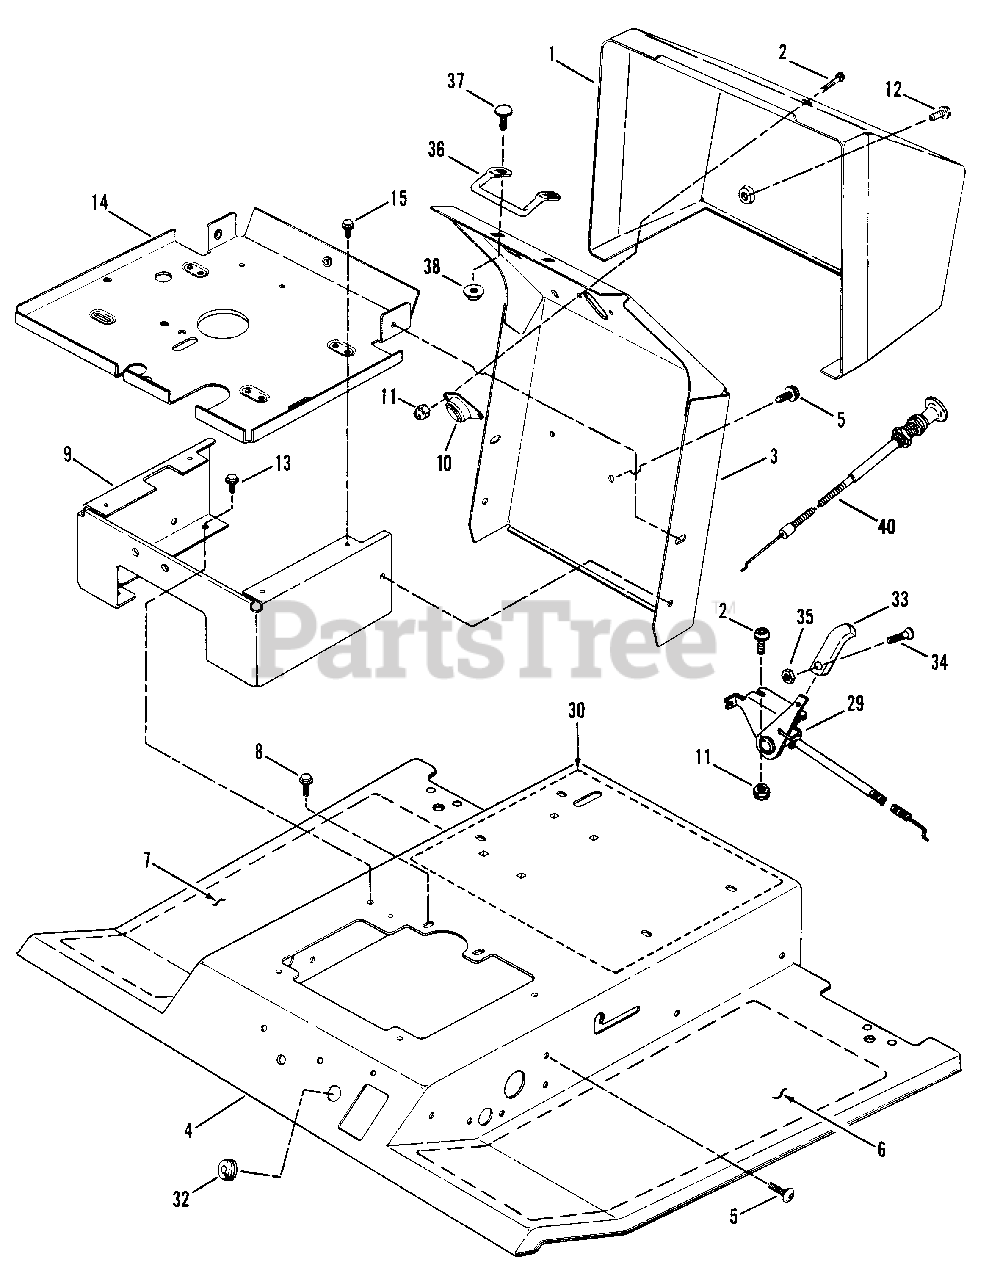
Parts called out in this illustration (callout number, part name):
1	PANEL, Dash
2	SCREW, 1/4-20 x 1" Phillips
3	SUPPORT, Steering Shaft
3	SUPPORT, Steering Shaft w/choke
4	CHANNEL, Foot Rest
5	SCREW, 5/16-18 x 7/8" Self-Tapping (Torx)
6	TREAD, Left Side (Non-Skid)
7	TREAD, Right Side (Non-Skid)
8	SCREW, 5/16-18 x 5/8" Self-Tapping
9	MOUNT, Fuel Tank/Battery
10	FLANGE ASSM'Y., Steering Shaft .75" ID Bearing
11	NUT, 1/4-20 Hex
12	SCREW, #10-24 x 1/2" Self-Tapping
13	SCREW, 5/16-18 x 1/2" Self-Tapping
14	PLATE, Fuel Tank & Battery Mount
15	SCREW, 1/4-20 x 1/2" Self-Tapping
29	CONTROL, Throttle 41.6" Long (Kohler 12.5 & 14 HP Engines)
29	CONTROL, Throttle 28.0" Long (Briggs 16 HP Engines)
30	DECAL, Caution & Instruction (No Longer available)
32	GROMMET, 5/16 I.D. for .75 Hole (No Longer available)
33	HANDLE, Throttle Control
34	SCREW, #8-32 x 3/8" Recessed Fillister Head
35	NUT, #8-32 Hex
36	ROD, Hood Latch
37	BOLT, 1/4-20 x 5/8" Flat Head Carriage
38	NUT, 1/4-20 Hex Flange Lock
